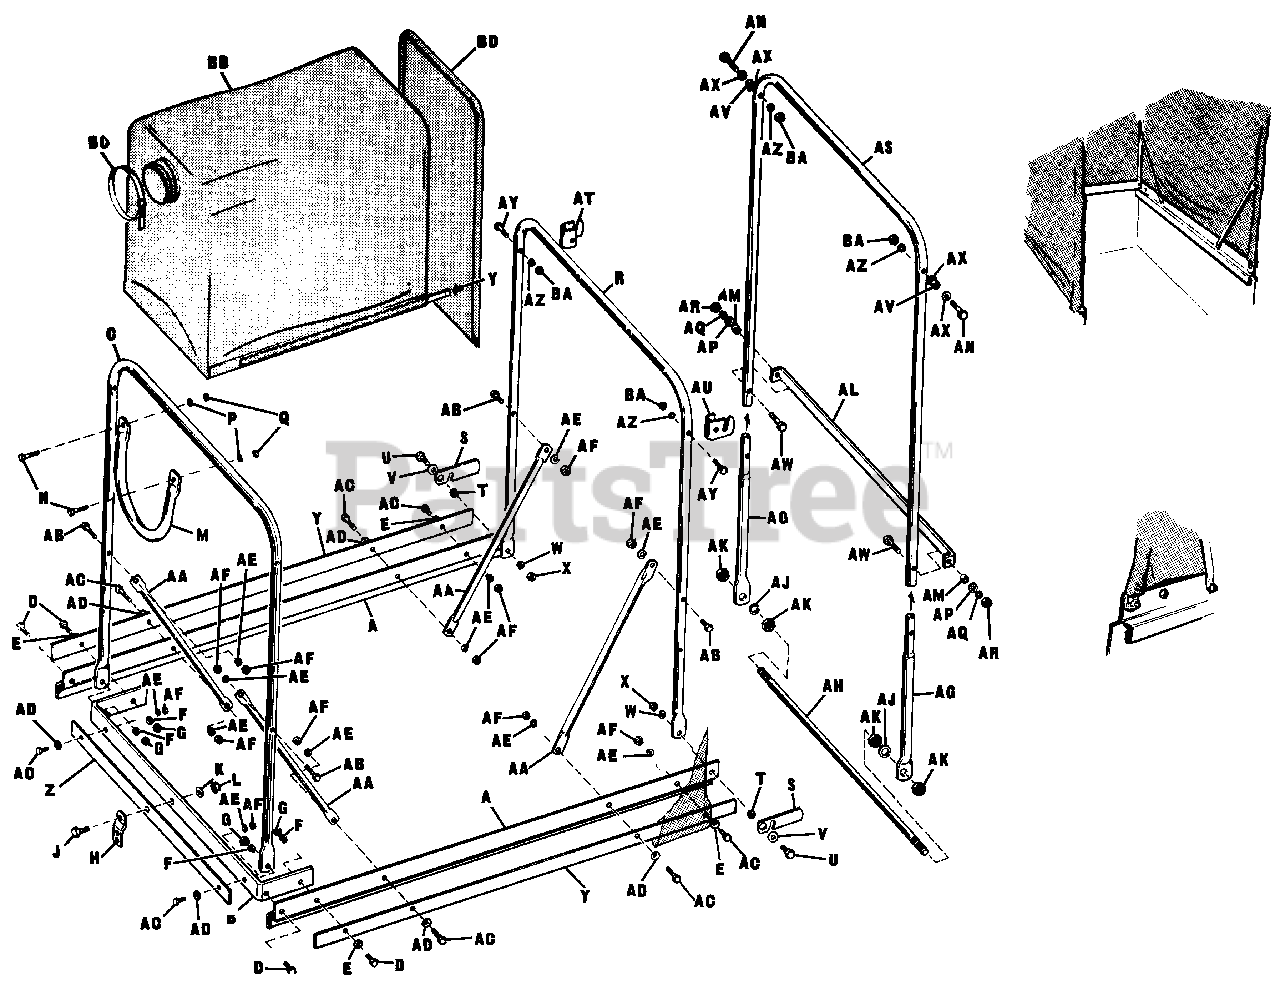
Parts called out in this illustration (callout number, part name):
A	"Z" Bar, Side
B	Front Bar
C	Front and Rear Upright
D	Hex Capscrew, 5/16"-18 x 1" lg.
E	Plain Washer, 5/16"
F	Lock Washer, 5/16"
G	Hex Nut, Full, 5/16"-18
J	Hex Capscrew, 3/8"-16 x 1" lg.
K	Plain Washer, 3/8"
L	Hex Lock Nut, Full, 3/8"-16
M	Hose Support
N	Hex Capscrew, 1/4"-20 x 1-1/4 lg.
P	Lock Washer, 1/4"
Q	Hex Nut, Full, 1/4"-20
R	Front and Rear Upright
S	Rear Door Latch
U	Hex Capscrew, 5/16"-18 x 7/8" lg.
V	Plain Washer, 5/16"
W	Lock Washer, 5/16"
X	Hex Nut, Full, 5/16"-18
Y	Hold Down Strip, Side
Z	Hold Down Strip, Front
AA	Cross Brace Tube
AB	Hex Capscrew, 1/4"-20 x 1-1/4" lg.
AC	Hex Capscrew, 1/4"-20 x 3/4" lg.
AD	Plain Washer, 1/4"
AE	Lock Washer, 1/4"
AF	Hex Nut, Full, 1/4"-20
AG	Tube, Rear Door
AH	Rod, Rear Door
AJ	Lock Washer, 1/2"
AK	Hex Nut, Full, 1/2"-13
AL	Bar, Rear Door
AN	Hex Capscrew, 1/4"-20 x 1-3/4" lg.
AP	Plain Washer, 1/4"
AQ	Lock Washer, 1/4"
AR	Hex Nut, Full, 1/4"-20
AS	Top Rear Door
AT	Catch, Door, R.H.
AU	Catch, Door, L.H.
AW	Hex Capscrew, 1/4"-20 x 1-3/4" lg.
AX	Plain Washer, 1/4"
AY	Hex Capscrew, 1/4"-20 x 1-1/4" lg.
AZ	Lock Washer, 1/4"
BA	Hex Nut, Full, 1/4"-20
BC	Hose Strap
